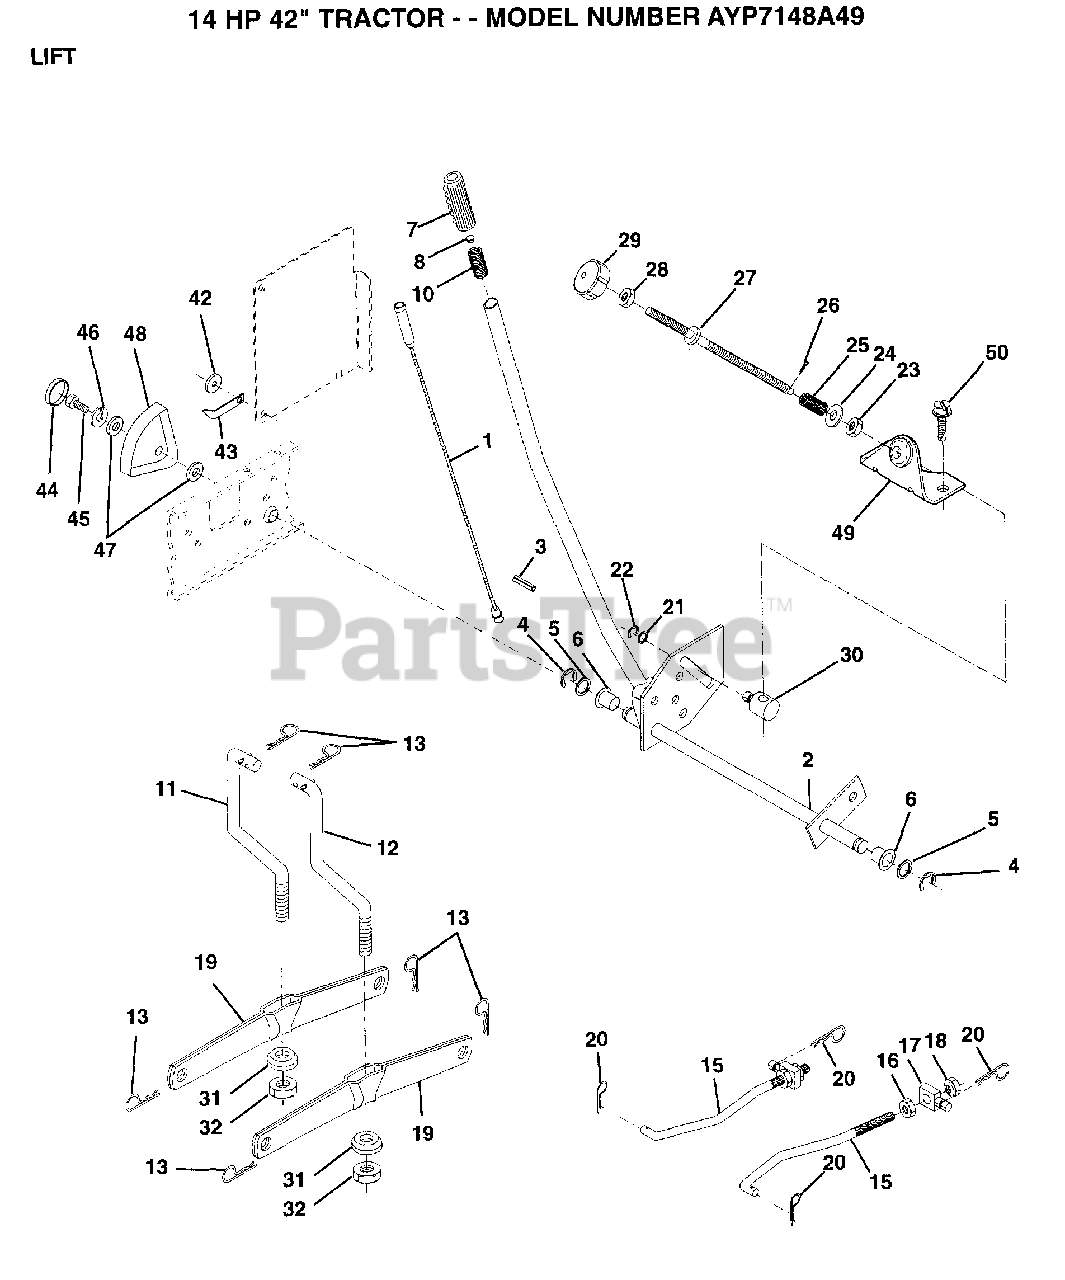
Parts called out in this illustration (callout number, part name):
1	WIRE ASM
2	HANDLE.LIFT.LH.
3	PIN GROOVE
5	WASHER
6	NYLON BEARING
7	GRIP HANDLE
15	LINK.FRONT
16	NUT
17	TRUNION
18	NUT.LK.W/WSH.1/2.
19	ARM SUSP REAR
20	RETAINER.SPRING
21	WASHER
22	KLIP RING
23	NUT T
24	WASHER
25	SPRING T
28	NUT
29	KNOB INF 3/8-16
30	TRUNION LT
31	BEARING PVT LH
32	NUT.LOCK.3/8-24
42	WASHER T
43	POINTER HGT IND
44	"PLUG,HOLE"
46	LOCKWASHER
47	WASHER
48	HEIGHT INDICATOR
49	BRACKET STOP INF
50	SCREW LT
